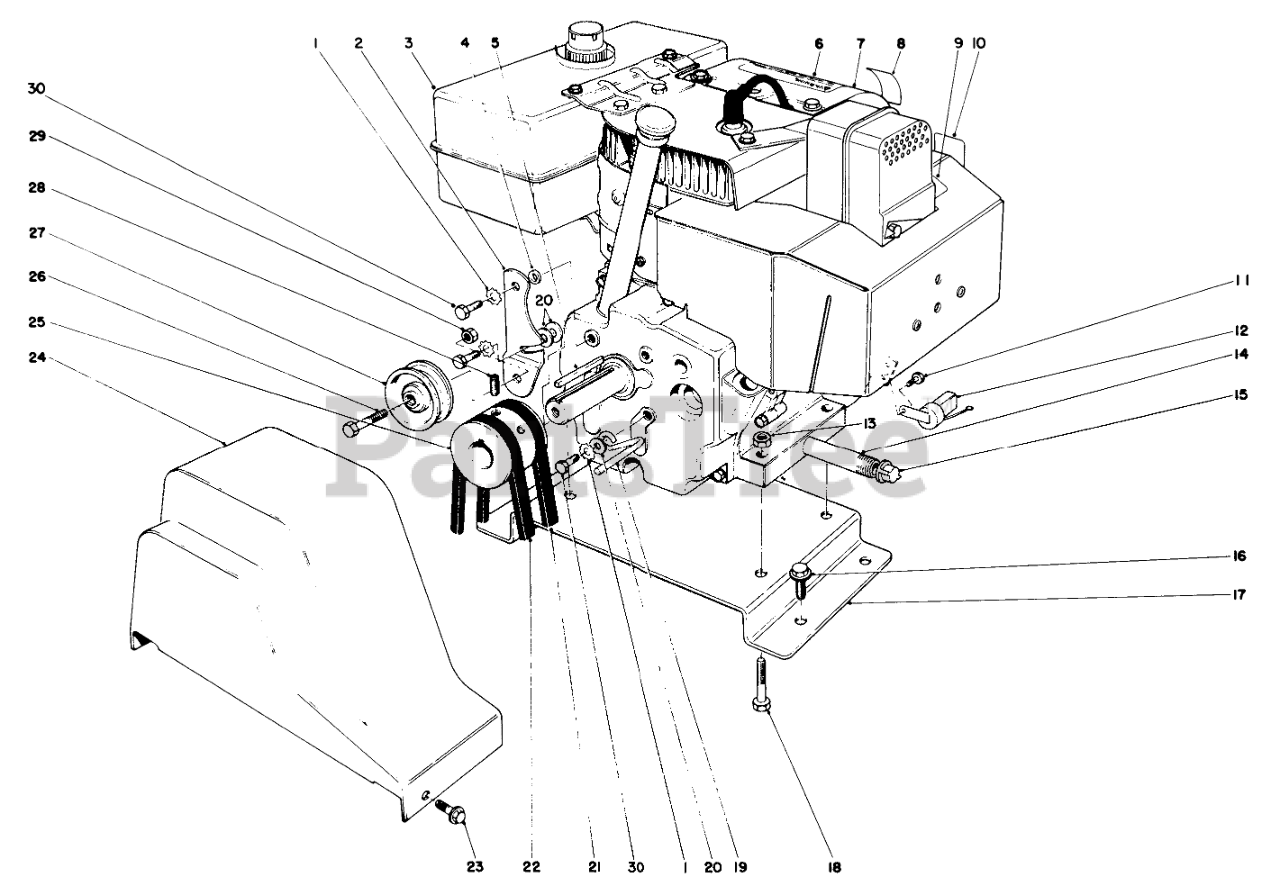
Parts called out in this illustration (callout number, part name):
1	WASHER-LOCK
2	ENGINE IDLER ARM
3	Fuel Tank w/Cap
4	SPACER
6	Decal-Hazards Caution
8	DECAL-PRIMER
9	HOT SURFACE DECAL
10	CHOKE DECAL
11	SCREW-HWH
12	INTERLOCK MODULE
13	NUT-LOCK, NI
14	NIPPLE-PIPE
15	CAP-PIPE
16	SCREW-HWHTF
17	Plate ngine Mounting
18	SCREW-HH
19	BELT RETAINER
20	WASHER-PLAIN
21	V-BELT
22	V-BELT
23	SCREW-HWH
24	BELT GUARD
25	ENGINE PULLEY
26	SCREW-HH
27	PULLEY-IDLER
28	SETSCREW
29	NUT-LOCK, NI
30	SCREW-HH
